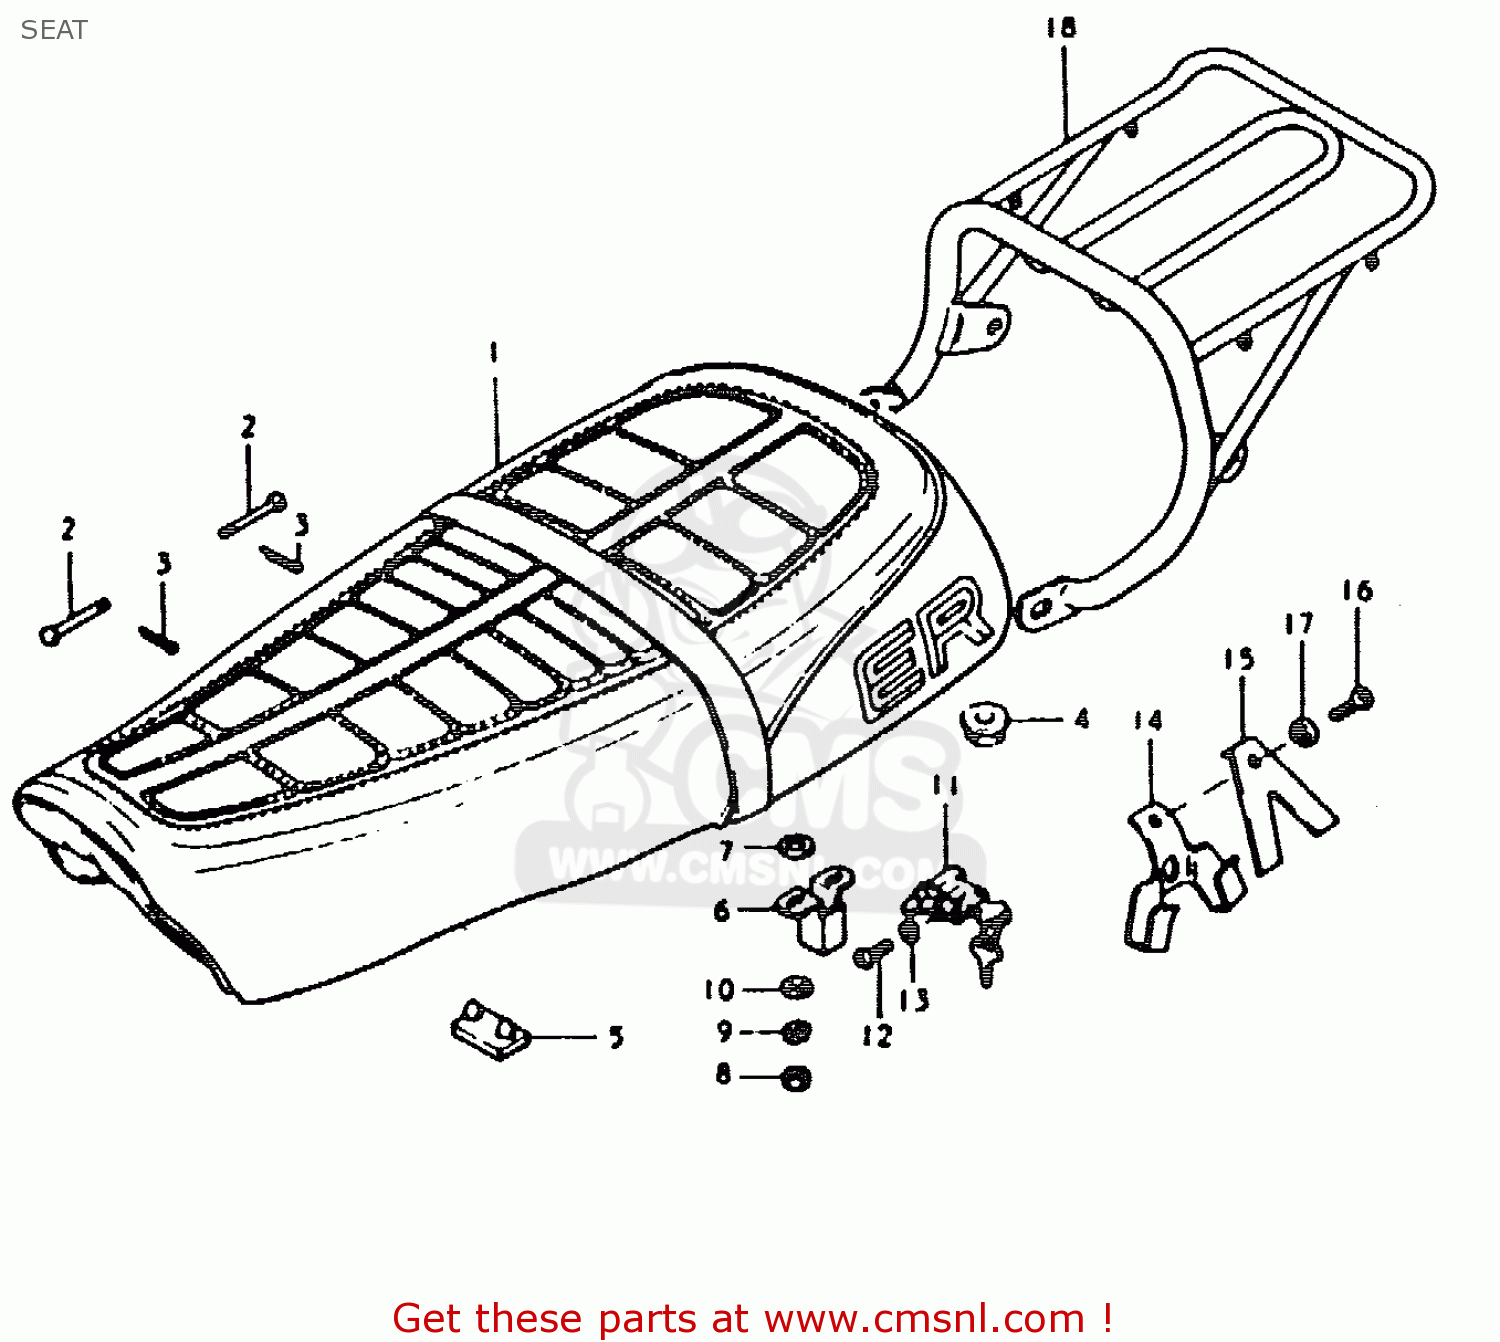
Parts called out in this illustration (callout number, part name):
1	SEAT ASSY
2	PIN
3	PIN
4	CUSHION
5	CUSHION
6	PLATE,CLAMP GUIDE
7	WASHER(8.5X18X1)
8	NUT
9	LOCK WASHER
10	WASHER
11	LOCK ASSY,SEAT
12	SCREW
13	LOCK WASHER
14	HOLDER,HELMET
15	SPRING OPT
16	SCREW 6X12
17	LOCK WASHER
18	CARRIER,SPORT
